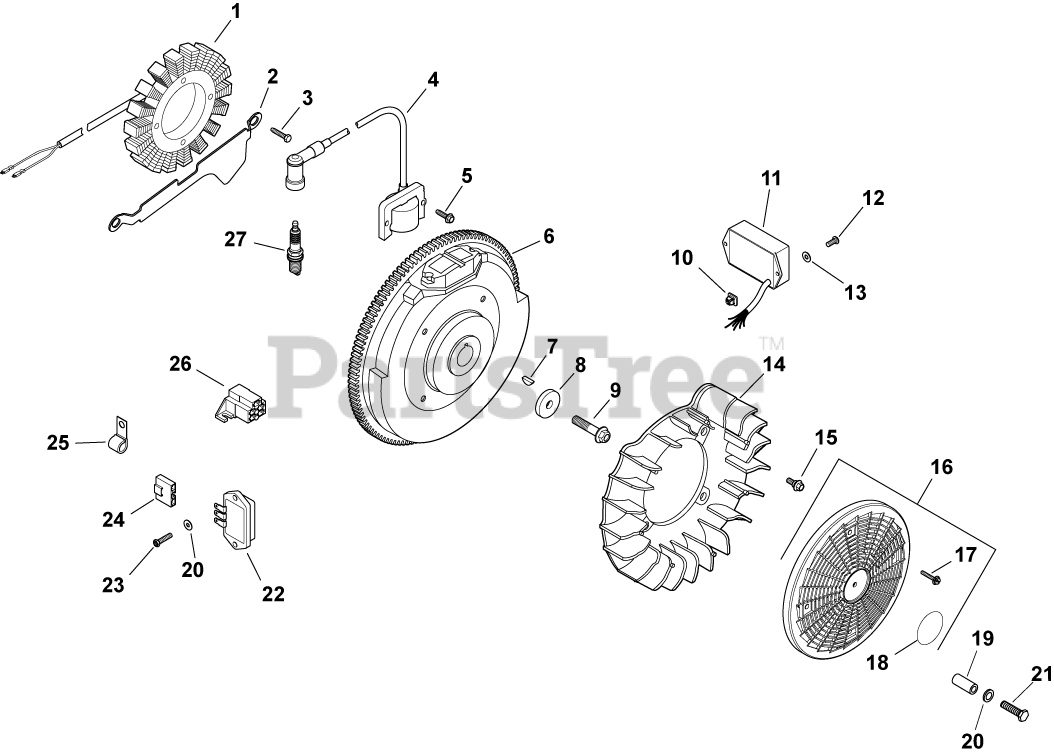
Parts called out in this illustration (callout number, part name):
1	KIT, 15 / 20 AMP STATOR
2	BRACKET, STATOR WIRE
3	SCREW, M5X0.8X25 - (#25086402S)
5	SCREW, SKT THD FRM M5X0.8X25
6	FLYWHEEL, PAINTED-USE 24 025 57-S
7	KEY, 3/16" X 5/8"
8	WASHER, FLAT 13/32"
9	SCREW, FLG M10X1.5X45 - (#25086361S)
10	NUT, PLASTIC
11	MODULE, SPEED ADVANCE-DISCONTINUED SEE PB265
12	SCREW, PHL HD #11-16X1/2"
13	WASHER, FLAT 1/4" (O.D. 1/2")
14	FAN (WITH HOLE)-USE 24 157 16-S
15	BOLT, SHOULDER
16	KIT, GRASS SCREEN
17	SCREW, FLG SEMS M4X.7X25
18	DECAL, GRASS SCREEN USE 24 113 499-S
19	SPACER - DISCONTINUED
20	WASHER, FLAT 3/16"
21	SCREW, SLT HD CAP M4X0.7X25
22	REG/RECT-15 AMP (KM)-USE 41 403 10-S
23	SCREW, PHL HD #11-16X7/8"
24	CONNECTOR, BODY (KM)-USE 25 155 41-S
25	CLIP, CABLE
26	CONNECTOR
27	PLUG, SPARK (STD)
